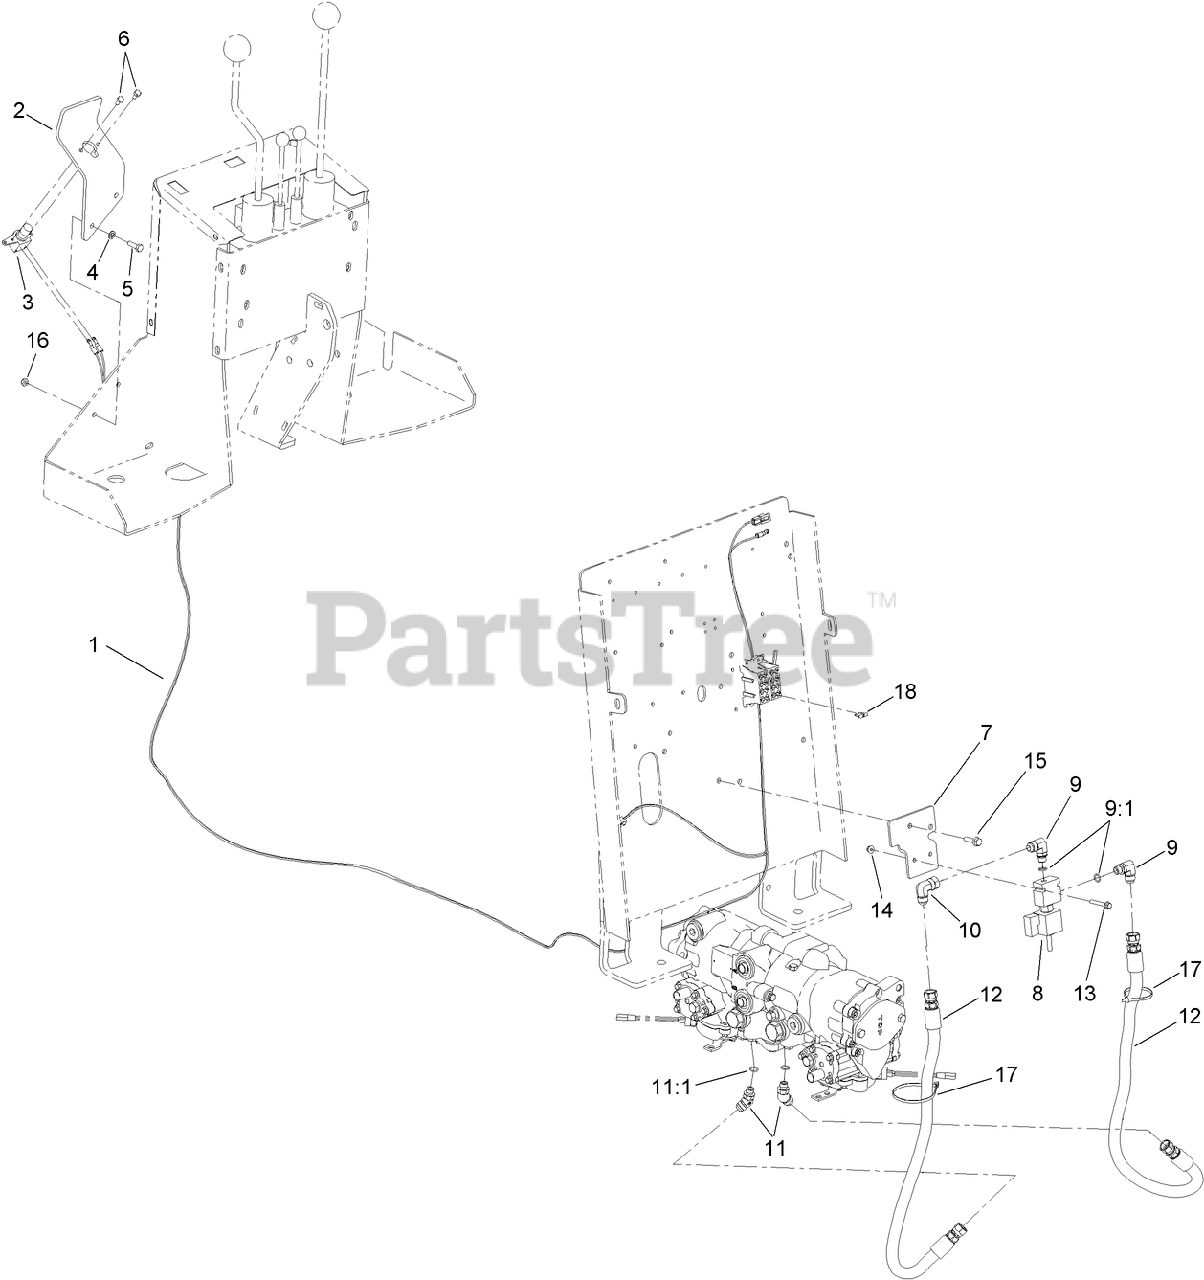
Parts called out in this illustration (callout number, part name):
1	HARNESS-WIRE, TOW VALVE
2	BRACKET-MOUNT, SWITCH
3	SWITCH-TOW VALVE
4	WASHER
5	SCREW-HH
6	SCREW-HH
7	BRACKET-SOLENOID,TOW VALVE
8	VALVE-POPPET (12V)
9	FITTING-HYD, 90 DEG
9:1	O-RING
10	FITTING-ELBOW, 90
11	FITTING-ELBOW, 45
11:1	O-RING
12	HYD HOSE ASM
13	SCREW-HHF
14	NUT-HF
15	SCREW-HHF
16	NUT-HEX
17	TIE-CABLE
18	FUSE-BLADE, 10 AMP
